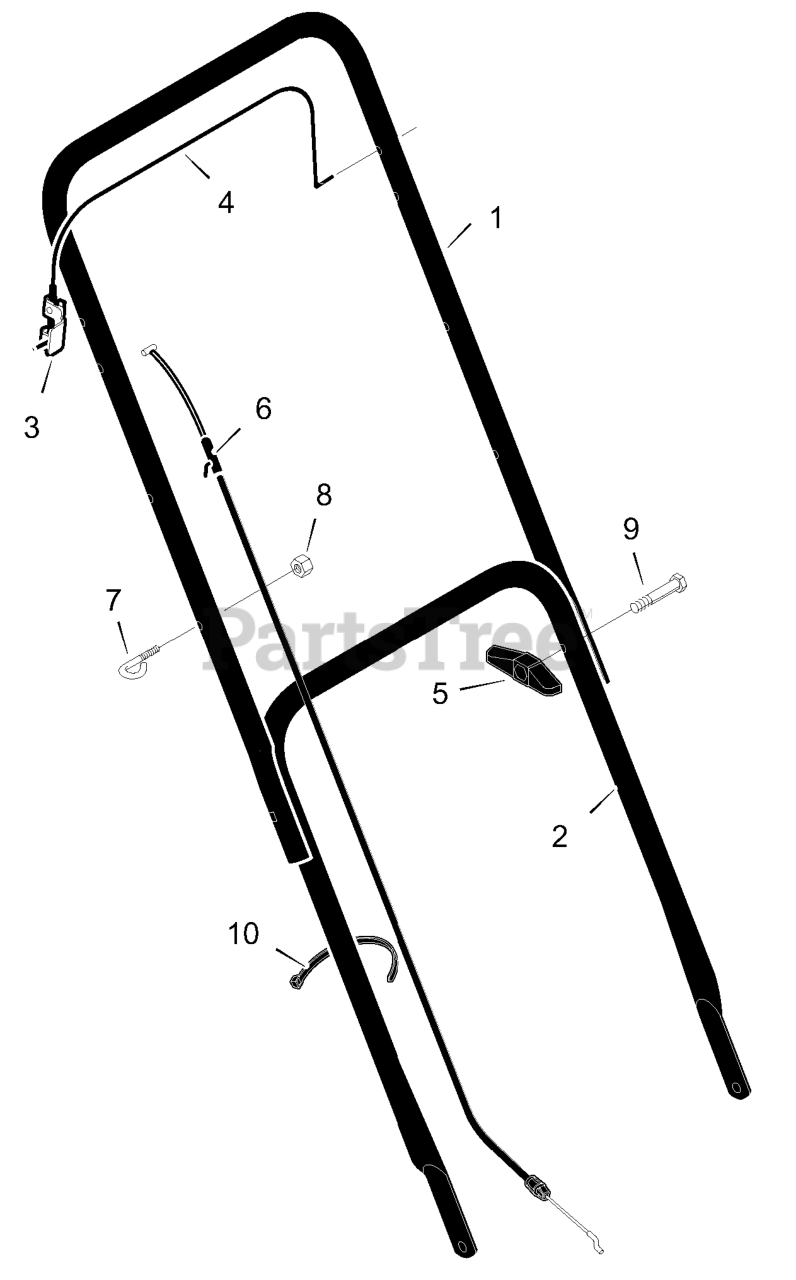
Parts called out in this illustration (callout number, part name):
1	Handle, Upper (Black)
2	Handle, Lower (Black)
3	Bracket, Stop Lever
4	Lever, Stop
5	Knob, Plastic
6	Engine Stop Cable
7	Guide, Rope
8	Locknut
10	Fastener, Cable
